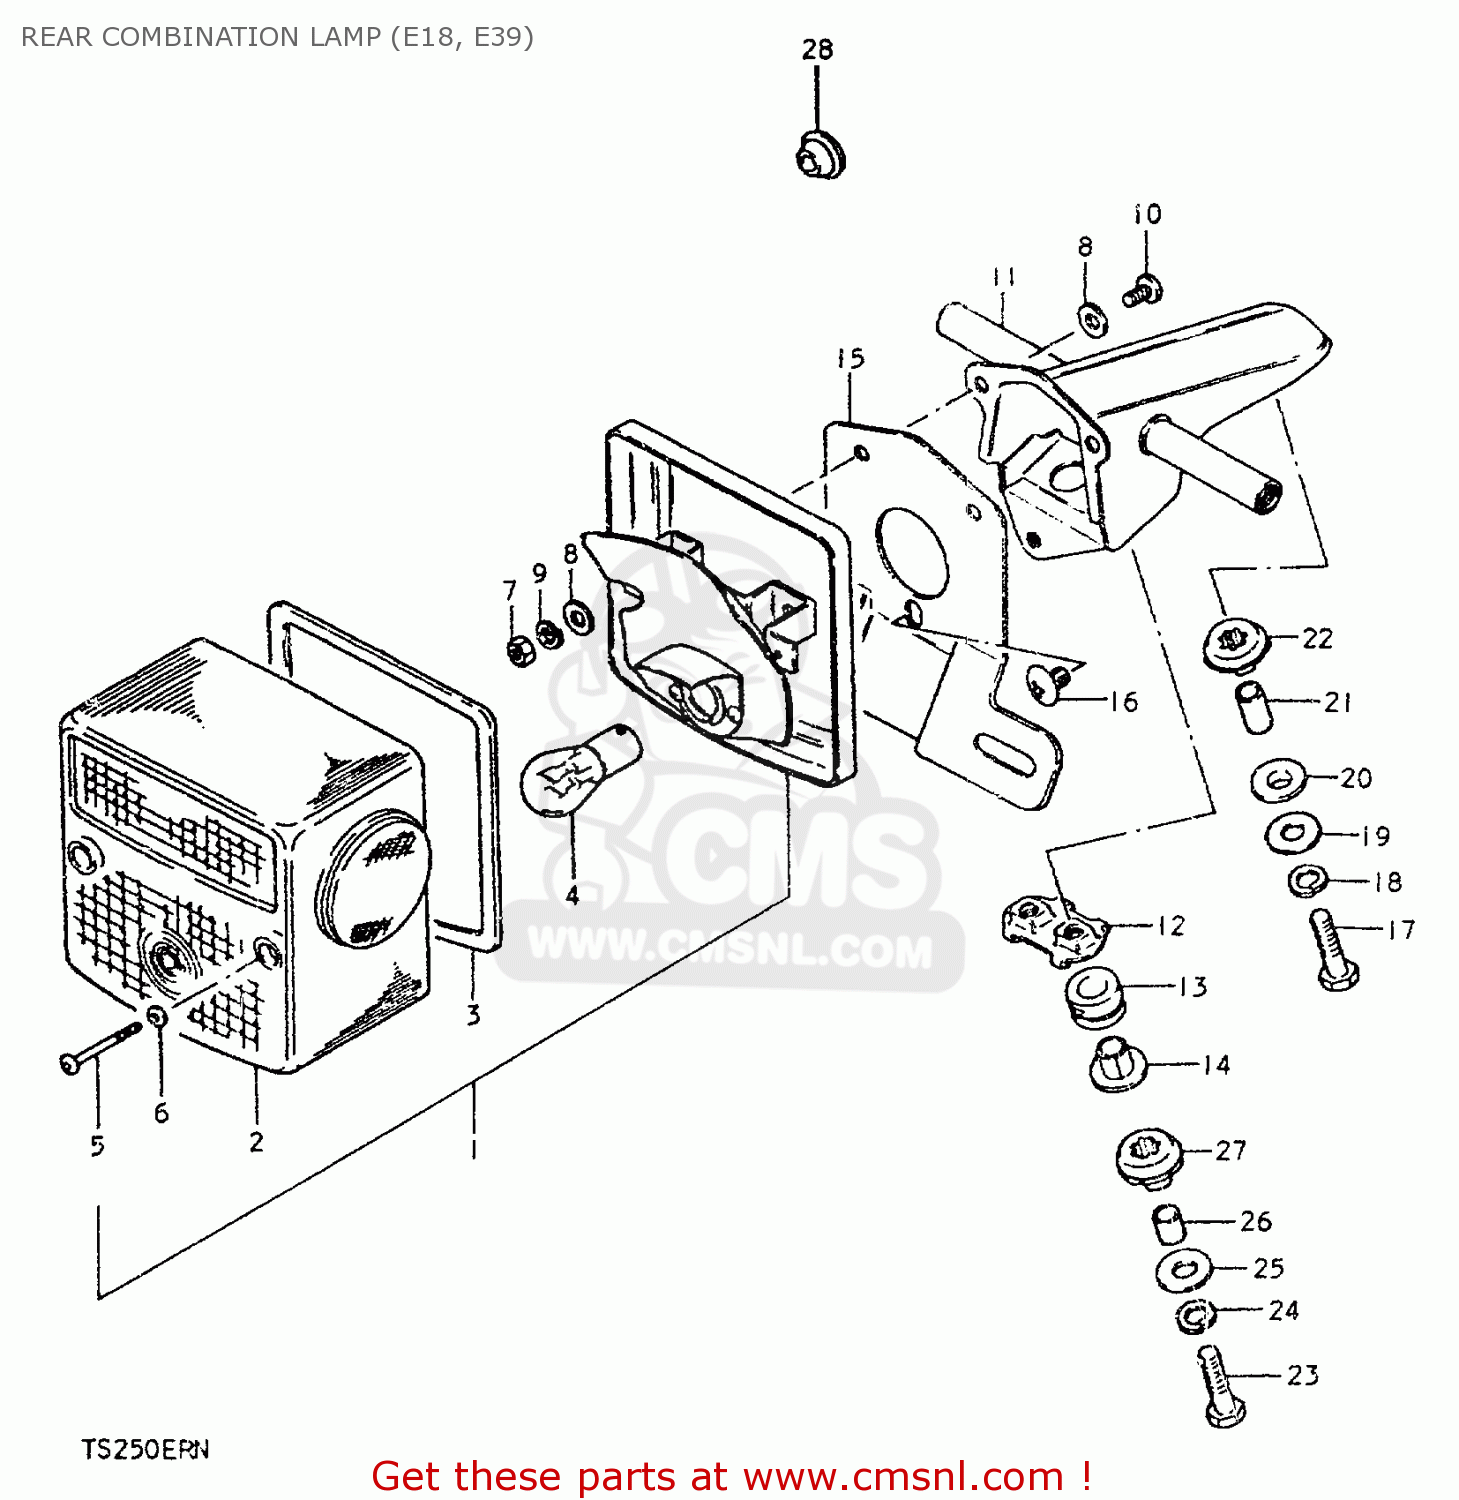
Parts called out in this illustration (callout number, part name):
1	LAMP UNIT, REAR COMBINATION
2	LENS
3	GASKET (NAS)
4	BULB (6V,21/5W)
5	SCREW (4X55)
6	GASKET (NAS)
7	NUT
8	WASHER
9	WASHER,LOCK
10	SCREW
11	BRACKET ASSY
12	PLATE
13	CUSHION
14	SPACER
15	PLATE, LICENSE
16	SCREW, PLATE
17	BOLT
18	LOCK WASHER
19	WASHER (6.5X20X1.2)
20	CUSHION
21	SPACER
22	CUSHION
23	BOLT
24	LOCK WASHER
25	WASHER (6.5X20X1.2)
26	SPACER
27	CUSHION
28	GROMMET
